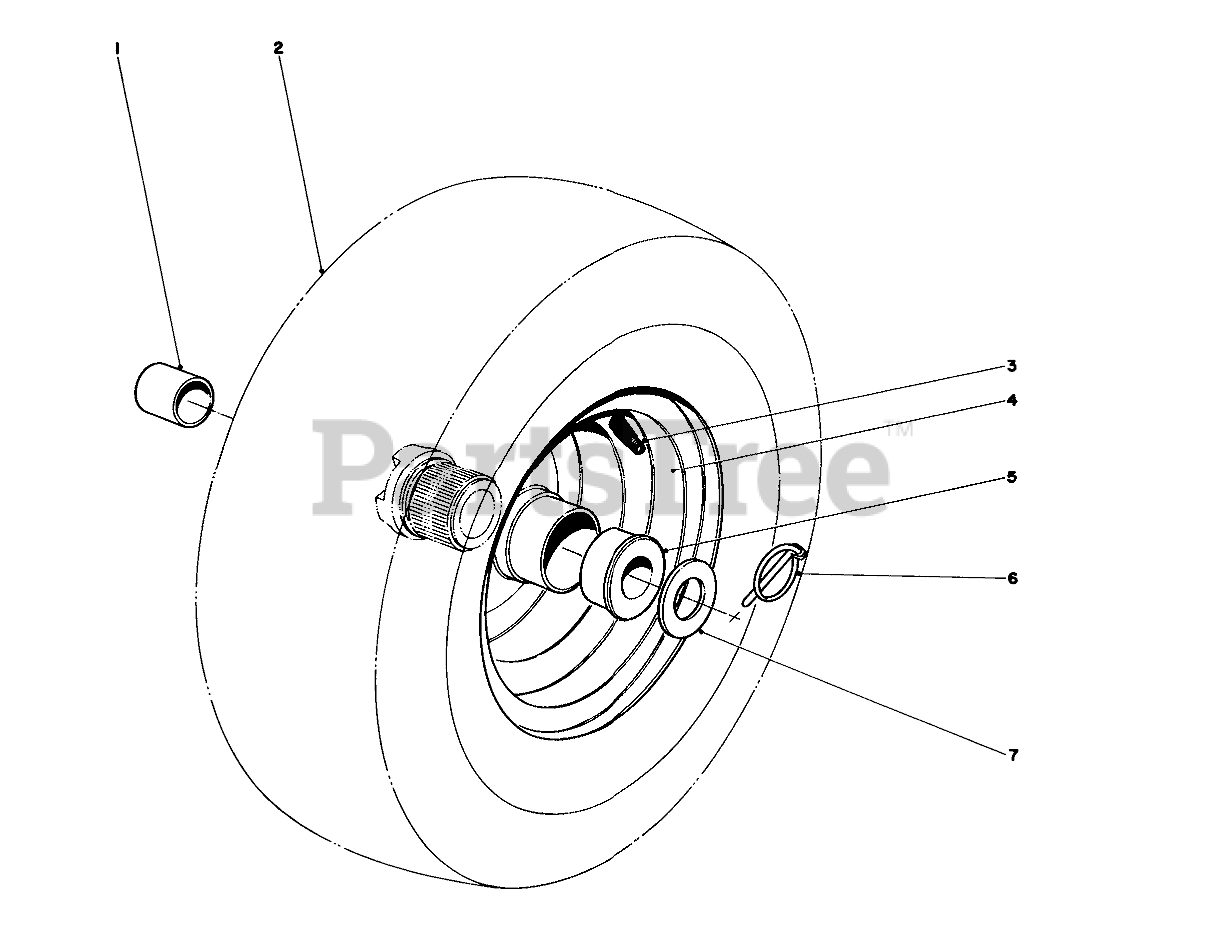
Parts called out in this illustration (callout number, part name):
1	.877ID X .750LG BSHG
2	Tire
3	STEM-VALVE
4	Wheel Rim
5	Bushing
6	PIN-LYNCH
7	WASHER-THRUST
